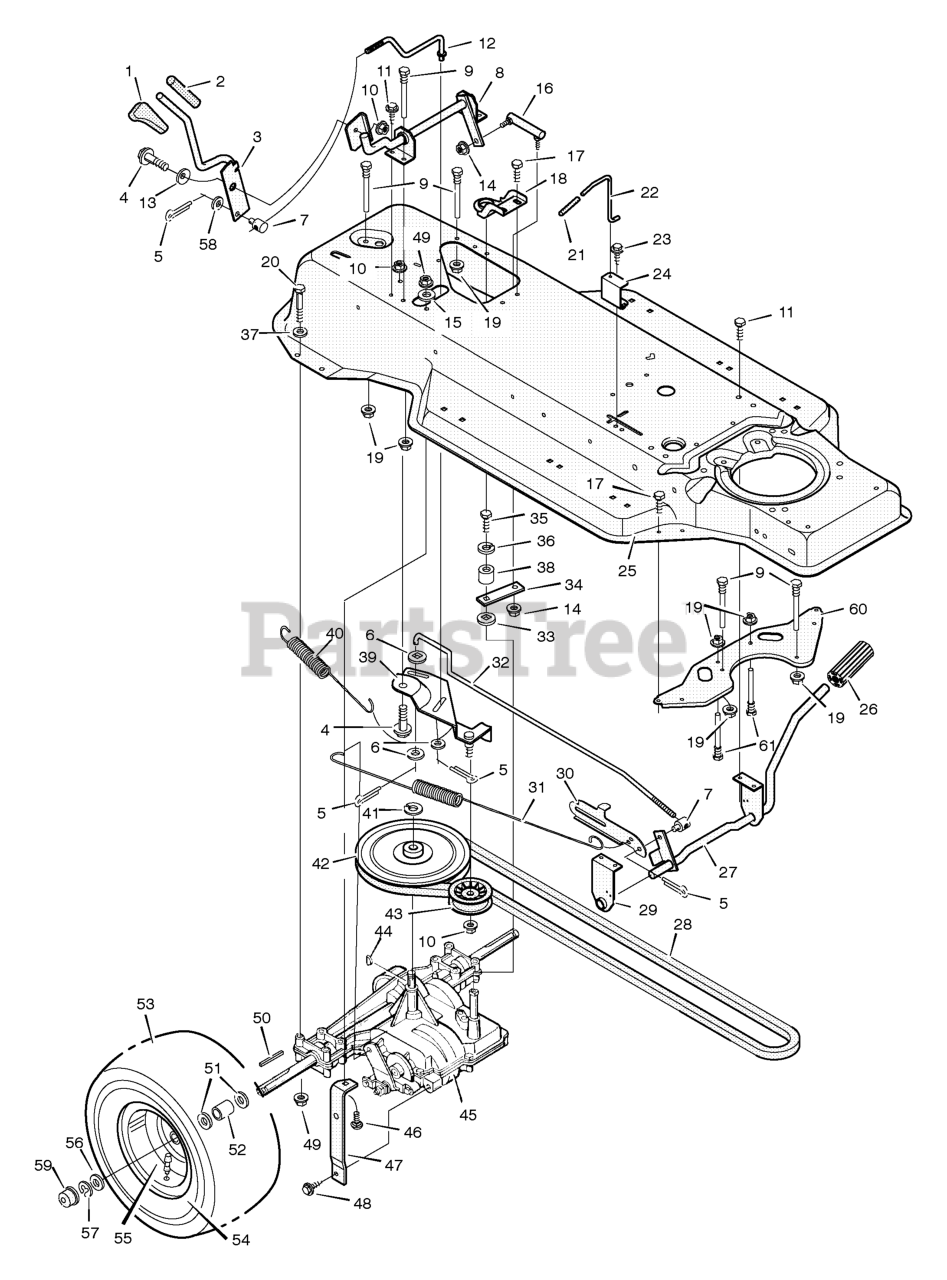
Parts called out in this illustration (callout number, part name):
1	Grip
3	Handle, Shift
4	Bolt, Shoulder
5	Pin, Cotter
6	Washer
7	Nut, Adjustable
8	Shifter Assembly
9	Guide, Belt
10	Locknut, Flange
12	Link, Clutch
13	Washer, Curved
14	Locknut, Flange
16	Link Assembly, Shifter
18	Bracket, Support
19	Nut, Flange
20	Bolt, Hex
22	Rod, Control
24	Guide, Bracket
25	Frame Assembly
26	Pedal, Clutch/Brake
27	Lever Assembly
28	Belt, Motion Drive
29	Bracket, Lever Support
30	Latch, Park Brake
31	Spring, Brake Extension
32	Rod, Clutch
34	Yoke, Shift
35	Bolt, Hex
36	Lockwasher
37	Washer
38	Pilot, Support
39	Bracket Assembly, Idler
40	Spring, Motion Drive
41	Ring, Retainer
42	Pulley, Motion Drive
43	Pulley, Backside Idler
44	Key, Woodruff
45	Transaxle, Peerless **
46	Bolt, Carriage
47	Support, Transaxle
49	Locknut, Flange
50	Key, Square
52	Spacer, Transaxle
53	Tire *
54	Wheel and Tire Assembly
55	Valve Stem
58	Washer
59	Hub Cap
60	Plate, Belt Guide
61	Guide, Belt
